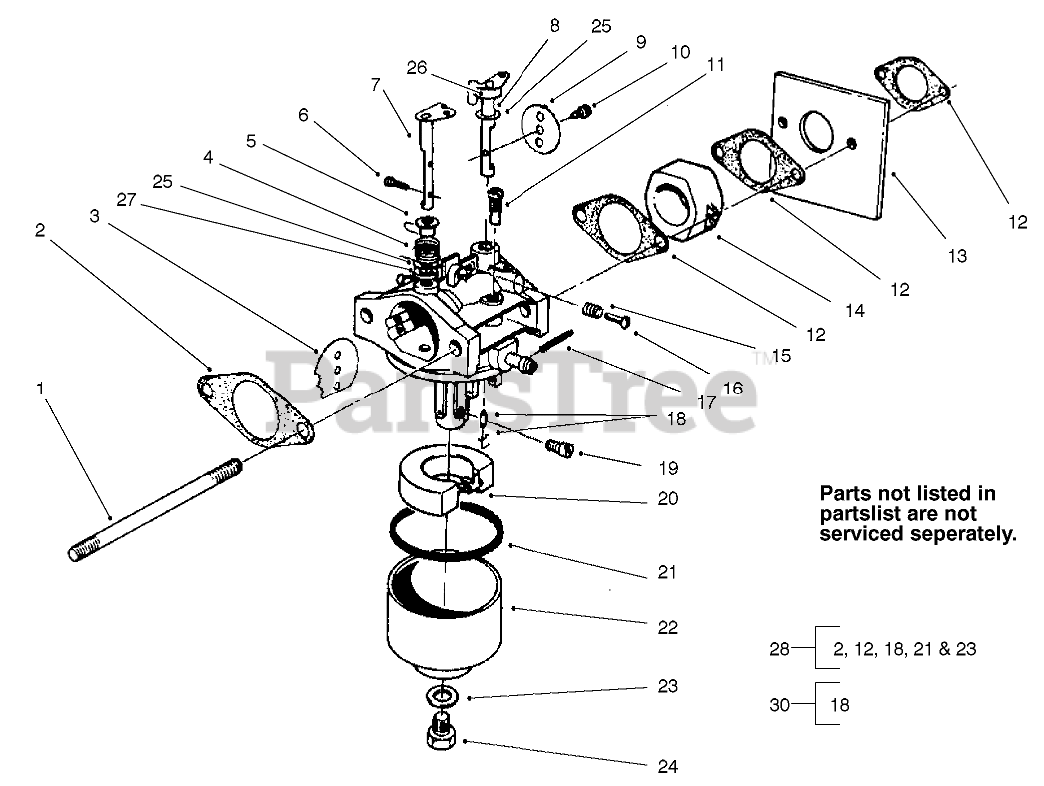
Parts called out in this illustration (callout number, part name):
1	STUD-CARBURETOR
2	GASKET-AIR CLEANER
3	PLATE
4	SPRING
5	BUSHING
6	SCREW
7	SHAFT-CHOKE
8	SHAFT
9	PLATE
10	SCREW
11	JET-PILOT
12	GASKET-CARB
13	SHIELD-CARBURETOR
14	INSULATOR-CARBURETOR
15	SPRING-PILOT SCREW
16	SCREW
17	PIN-HINGE
18	NEEDLE
19	JET-MAIN
19	JET-HIGH ALTITUDE
20	FLOAT
21	GASKET
22	BOWL - FLOAT
23	GASKET
24	SCREW
27	PACKING
28	KIT-CARBURETOR
30	NEEDLE-SEAT SET
